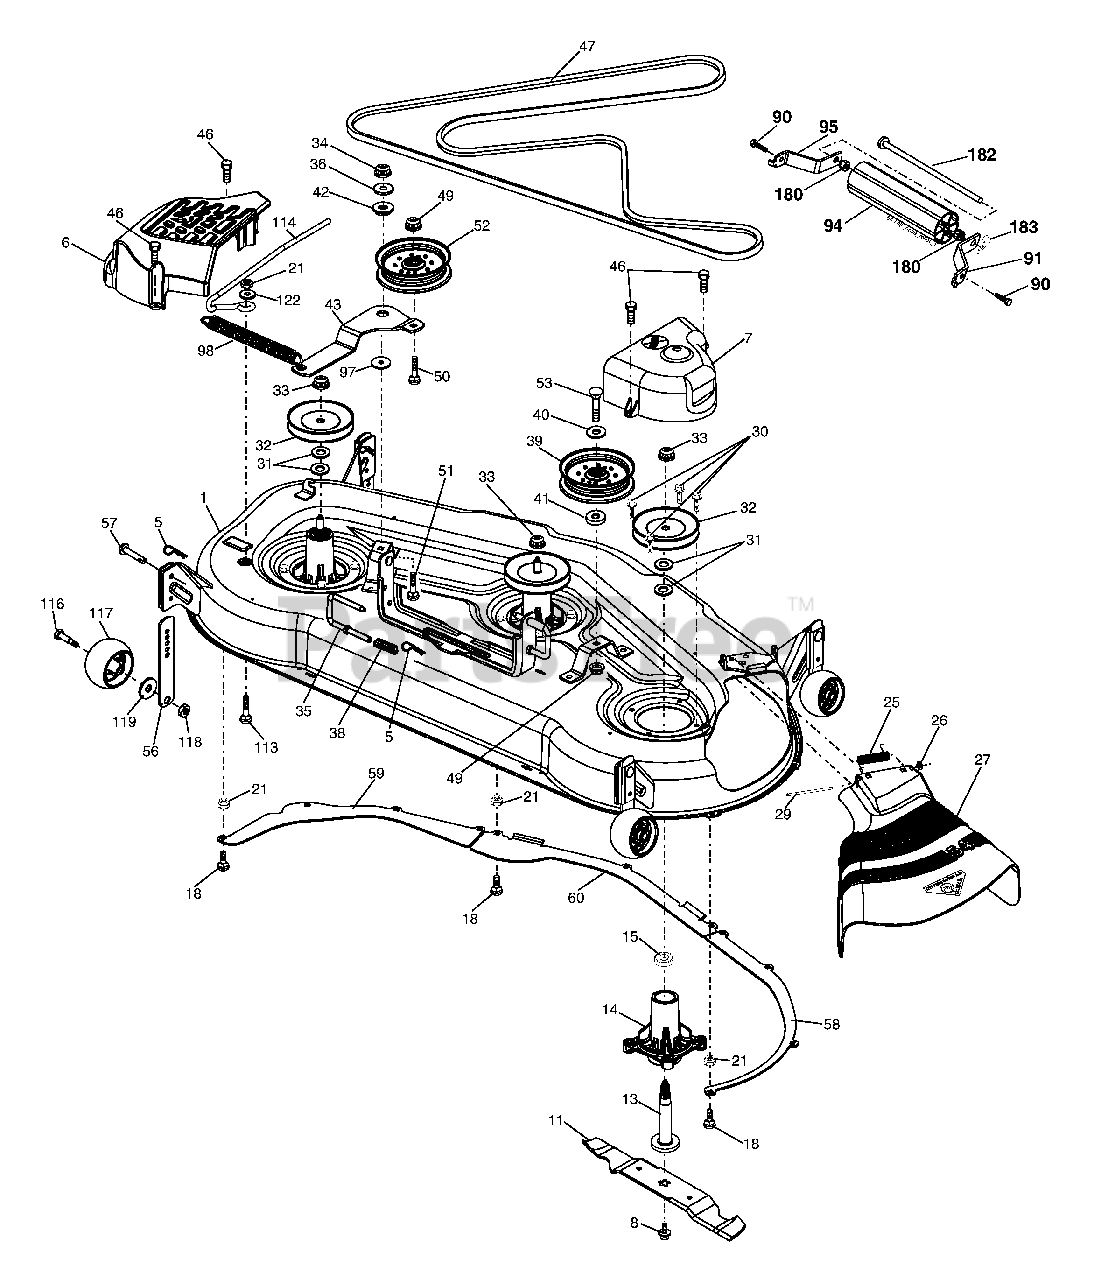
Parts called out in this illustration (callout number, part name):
1	Deck Weldment Mower
5	Retainer Spring
6	Cover Mandrel LH
7	Cover Mandrel RH
8	Bolt 7/16 Asm. Blade
11	Blade, Standard
13	Shaft Asm. w/Lower Bearing
14	Housing, Mandrel
15	Bearing, Ball, Mandrel
17	Bolt, Carriage 5/16-18 x 5/8
21	Nut, Crownlock 5/16-18 unc
25	Spring, Torsion
26	Nut, Push
27	Deflector Shield
29	Rod, Hinge
30	Screw, Thdroll Washer Head
31	Washer, Spacer Mower Vented
32	Pulley, Mandrel
33	Nut, Flg. Top Lock Cntr. 9/16
34	Nut
35	Pin Suspension Rear
36	Washer 13/32 x 13/16 x 16 Ga.
38	Spring Compression
39	Pulley, Idler, Stationary
40	Washer 13/32 x 12 Ga.
41	Washer 13/32 x 1-3/8 x 3 Ga.
42	Spacer, Retainer
43	Arm, Idler
46	Screw, Thdroll. 1/4-20 x 5/8
47	V-Belt, Mower, Secondary
49	Nut, Lock Flg. 3/8-16 unc
50	Bolt, Carr. 3/8-16 x 2
51	Bolt
52	Pulley Idler Clutching
53	Bolt Hex 3/8-16 unc x 2-1/4
56	Bar Pnt Adj.
57	Pin Head Rivet
58	Baffle Right
59	Baffle Left
60	Baffle Center
90	Bolt 5/16-18 x 1
91	Bracket Asm N Roller RH
94	Roller Nose 48"
95	Bracket Asm N Roller LH
97	Washer Hardened
98	Spring Clutch Drive
113	Bolt Rdhd Sqnk 5/16-18 x 3/4
114	Rod Tension Relief
116	Bolt, Shoulder
117	Gauge Wheel
118	Nut, Centerlock 3/8-16 unc
119	Washer 3/8 x 7/8 x 14 Ga.
122	Bushing Tension Relief
180	Nut 5/16-18
182	Rod Roller Nose Narrow
183	Retainer Spring
